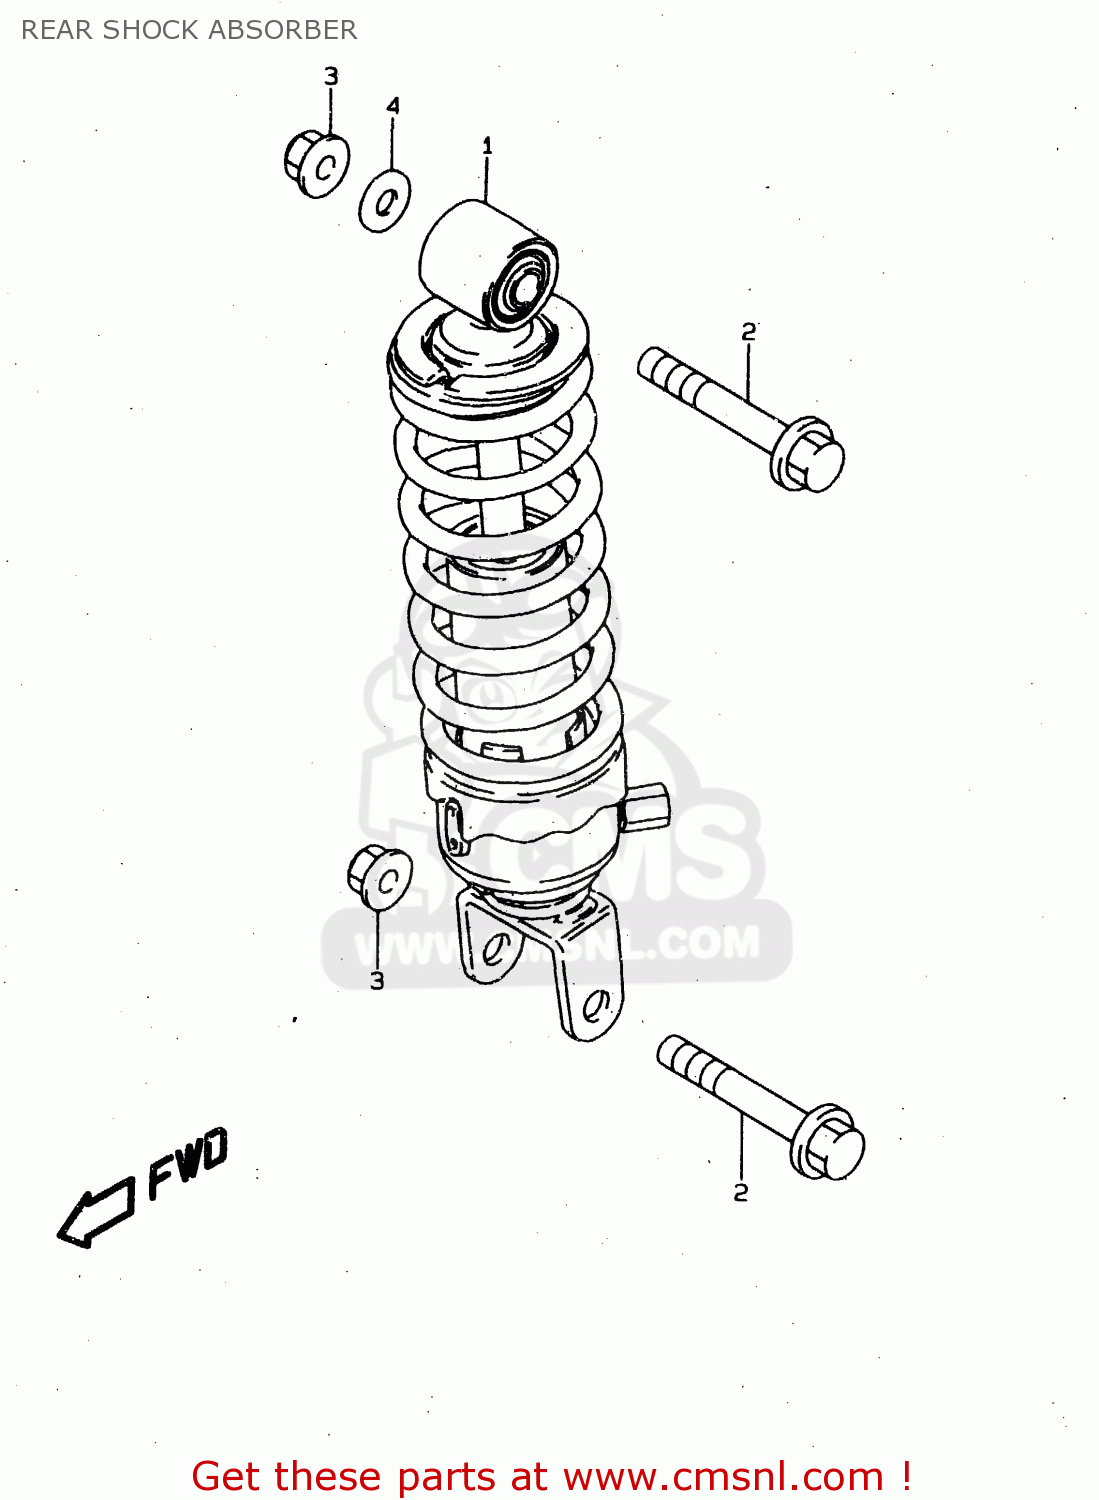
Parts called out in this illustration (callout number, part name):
1	ABSORBER ASSY,RR SHOCK
2	BOLT,RR SHOCK ABSORBER(10X51)
3	NUT
4	WASHER(10.5X22X1.6)
